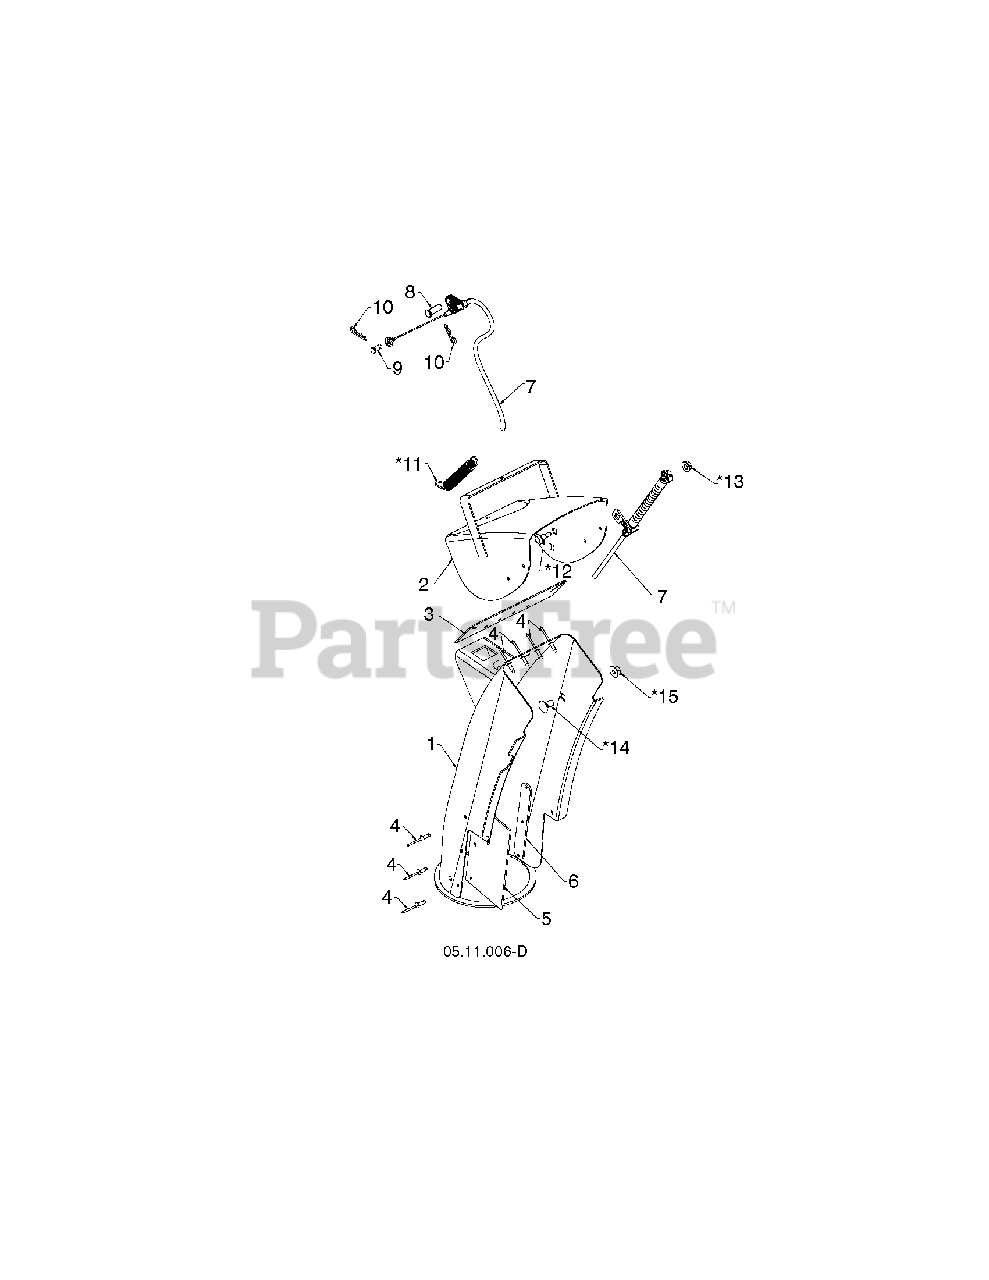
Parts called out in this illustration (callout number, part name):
3	SEAL.DEFLECTOR
4	RIVET BLIND
5	SHIELD.SNOW.CHUTE
6	STRAP.SHEILD.RETAINER
7	Deflector Chute Control Cable
8	Clevis Pin, 5/16 X .875
9	Clevis Pin, .25 X .31
10	Hair Pin, .059 X 1.125
12	Shoulder Bolt, 1/4
13	Flange Hex Lock Nut, 1/4-20 Large
14	Carriage Bolt, 5/16-18 X 5/8 Black
15	LOCKNUT-FLANGE 5/16-18
